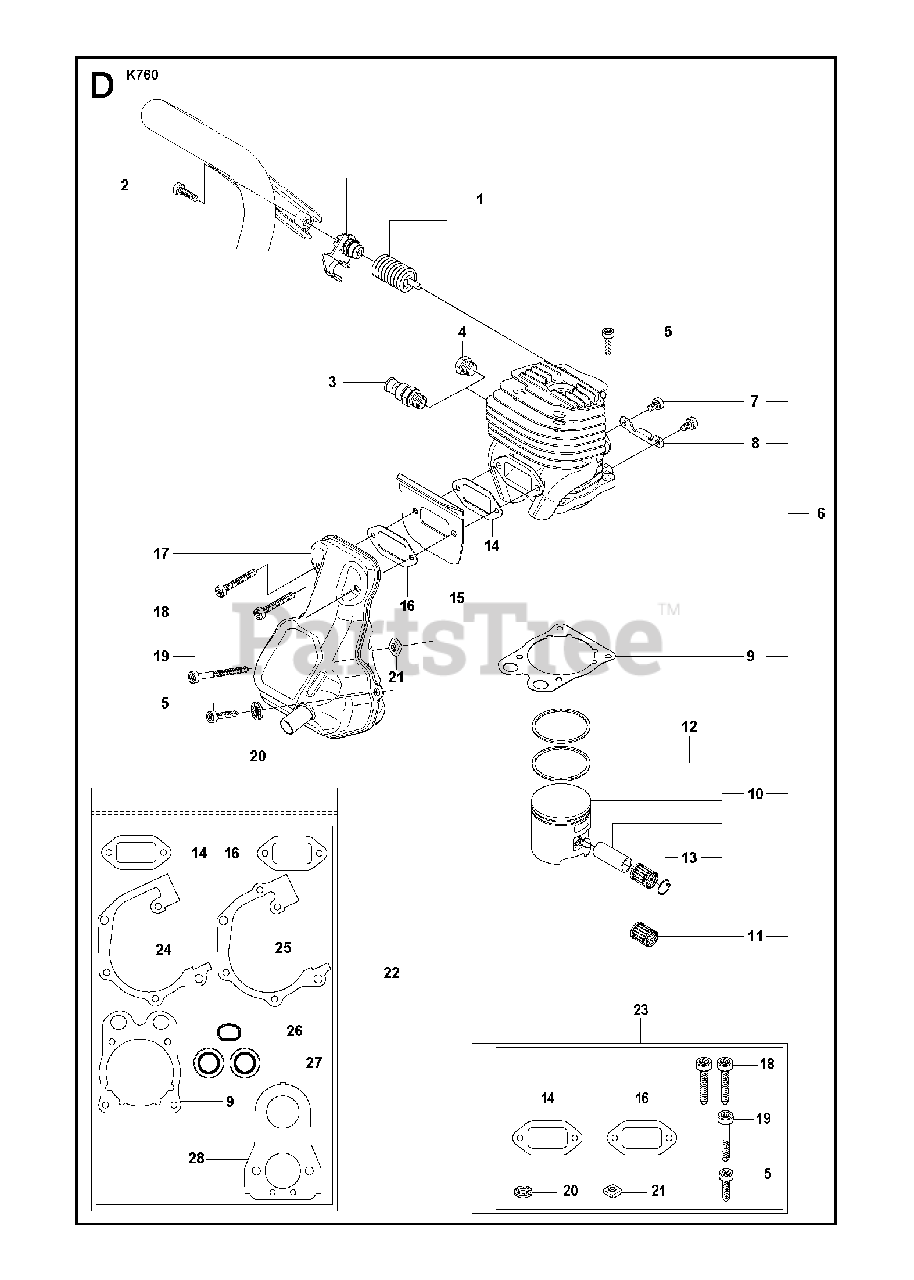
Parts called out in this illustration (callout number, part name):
1	ANTIVIBRATION ELEMENT
2	SCREW ITXSCM
3	DECOMPRESSION VALVE
5	SCREW ITXSCM
6	CYLINDER ASSYIncl. 7 - 11
7	SCREW ITXSCM
10	PISTON ASSYIncl. 12 - 13
11	NEEDLE BEARING
12	PISTON RING
15	COOLING AIR CONDUCTOR
16	GASKET
17	MUFFLER ASSY
18	SCREW ITXSCM
19	SCREW ITXSCM
22	GASKET KITIncl. 9, 14, 16, 24 - 28
23	MUFFLER KITIncl. 5, 14, 16, 18 - 21
27	SEALING RING
28	GASKET
